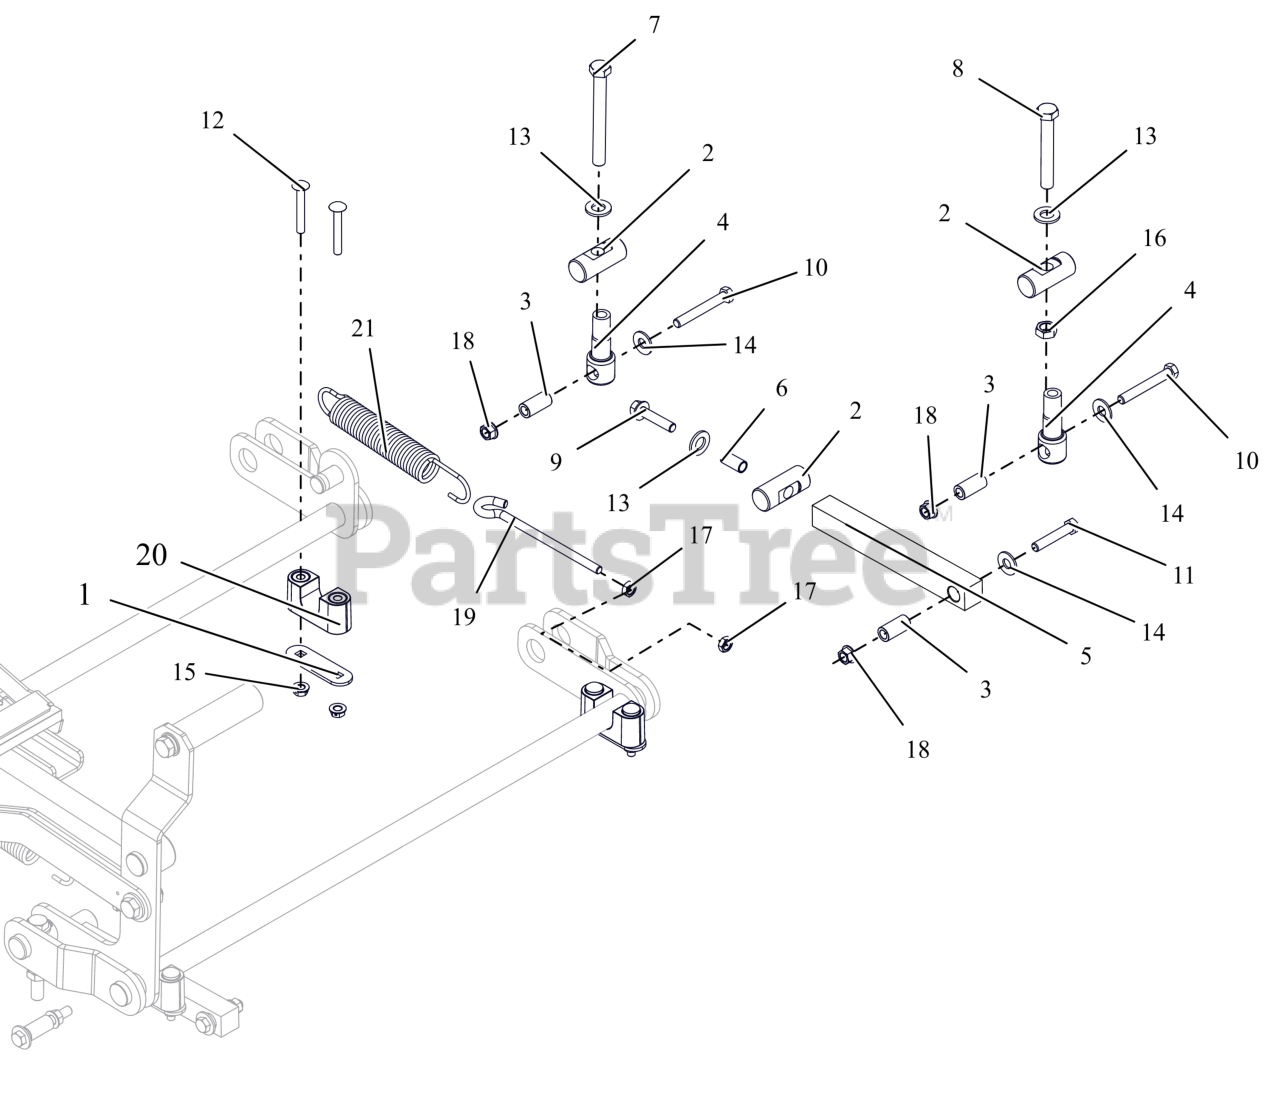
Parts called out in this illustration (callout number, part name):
1	PLATE, BEARING SUPPORT
2	PIN, DECK LIFT
3	SPACER, DECK LEVELING
4	LINK, DECK LIFT FORMED
5	LINK, DRAG
6	BSHG-SLV .385X.500X1.045
7	@BLT-HEX .5-13-4.5GR8 FULL THD
8	BLT-HEX .50-13X3.50 GR5 FTH
9	BLT,HEX-FLG .38-16X1.75 G5 ZCC
10	BLT-HEX .38-16X2.75 GR8 YWZC
11	@BLT-HEX .38-16X2.00 GR5 YWZC
12	BLT-RDHDSQSHNK .31-18X2.25 YWZ
13	FLATWASHER 1/2 SAE HARD 15906
14	@WSHR-FL-STL.438X1.00X.083 YWZ
15	@NUT-LK-CTR-FLG .31-18 YZ GR F
16	NUT-JAM .50-13 YWZC
17	NUT-HEX-JAM .375-16 YWZC
18	@NUT-LK-TOP-FLG .38-16 YWZC
19	BOLT,.38-16 X 5.25-.62 DIA EYE
20	ASM-BUSHING, DECK LIFT
21	SG-TENS .162X1.25X8.25 WLD 25
